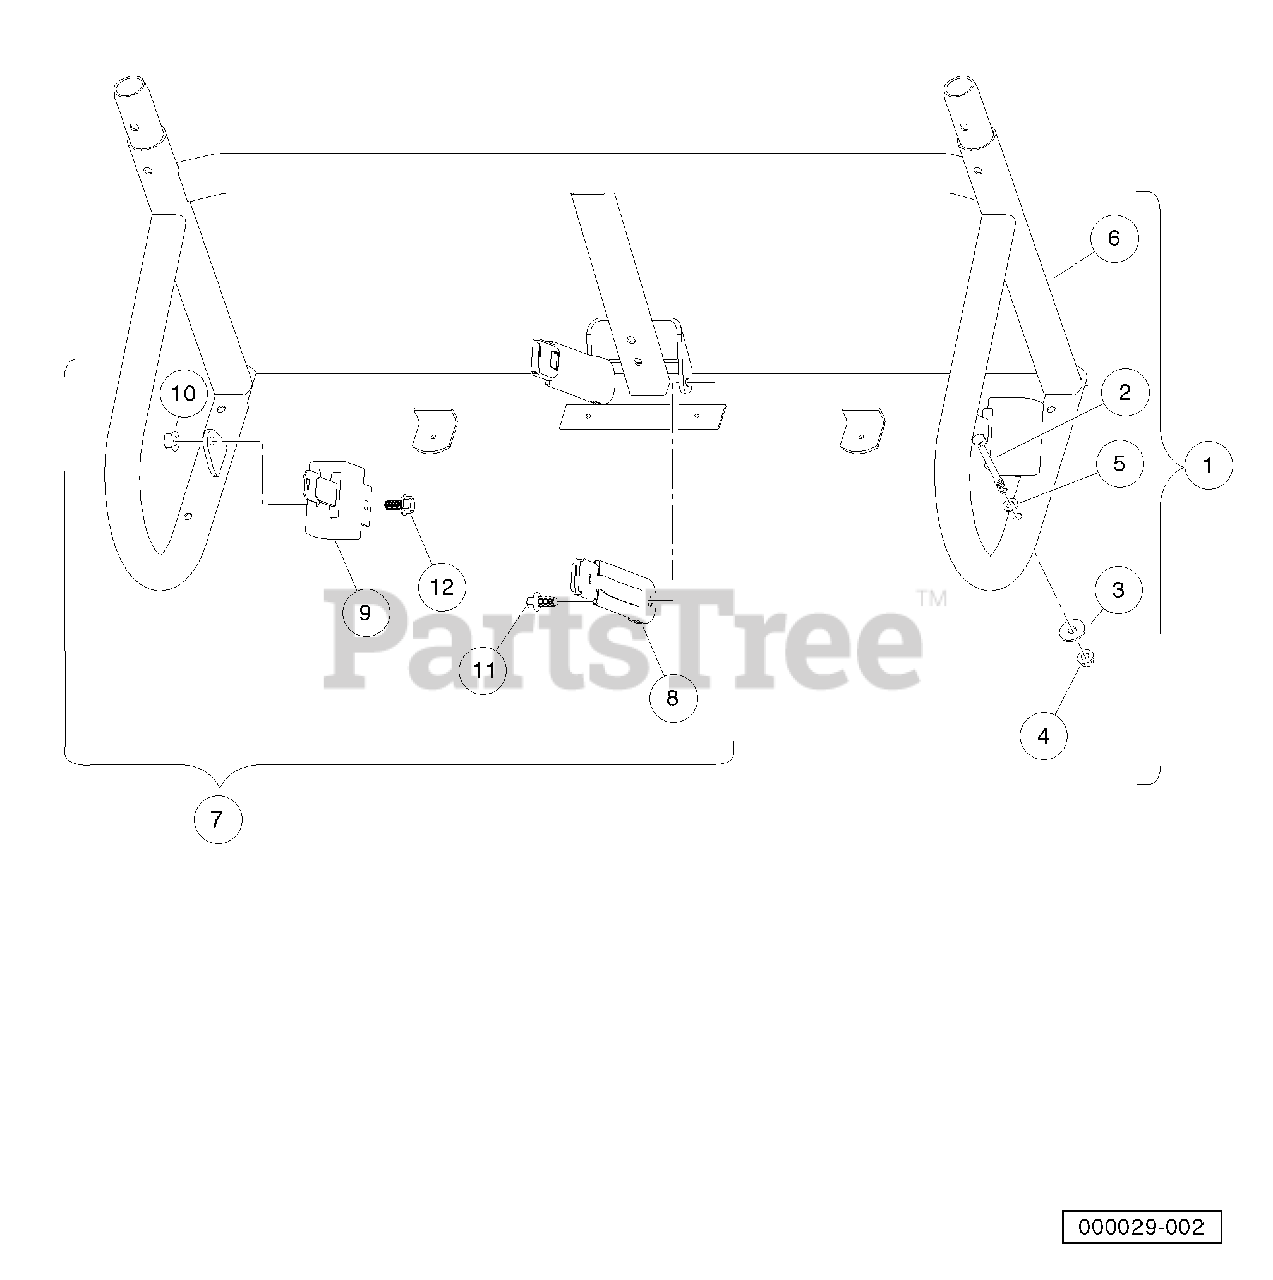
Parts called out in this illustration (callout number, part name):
1	Instl, Rops, Lower
2	Bolt, M10x1.50x100
3	Washer Hard,m10
4	Nut Flg M10 X 1.5 Mech Def
5	Washer, Hard, M10, Zn-Ni/Blk
6	Weldment,seat Support,hs,rops
7	Instl, Seat Belt, Restyle
8	Buckle, Seat Belt with Sleeve
9	Retractor, Seat Belt
10	Ln Flg, M12 X 1.75, Md, Black
11	Screw,m12x1.75x30 Thd Form Blk
12	Bolt Flg, M12x1.75 X 25 Black
